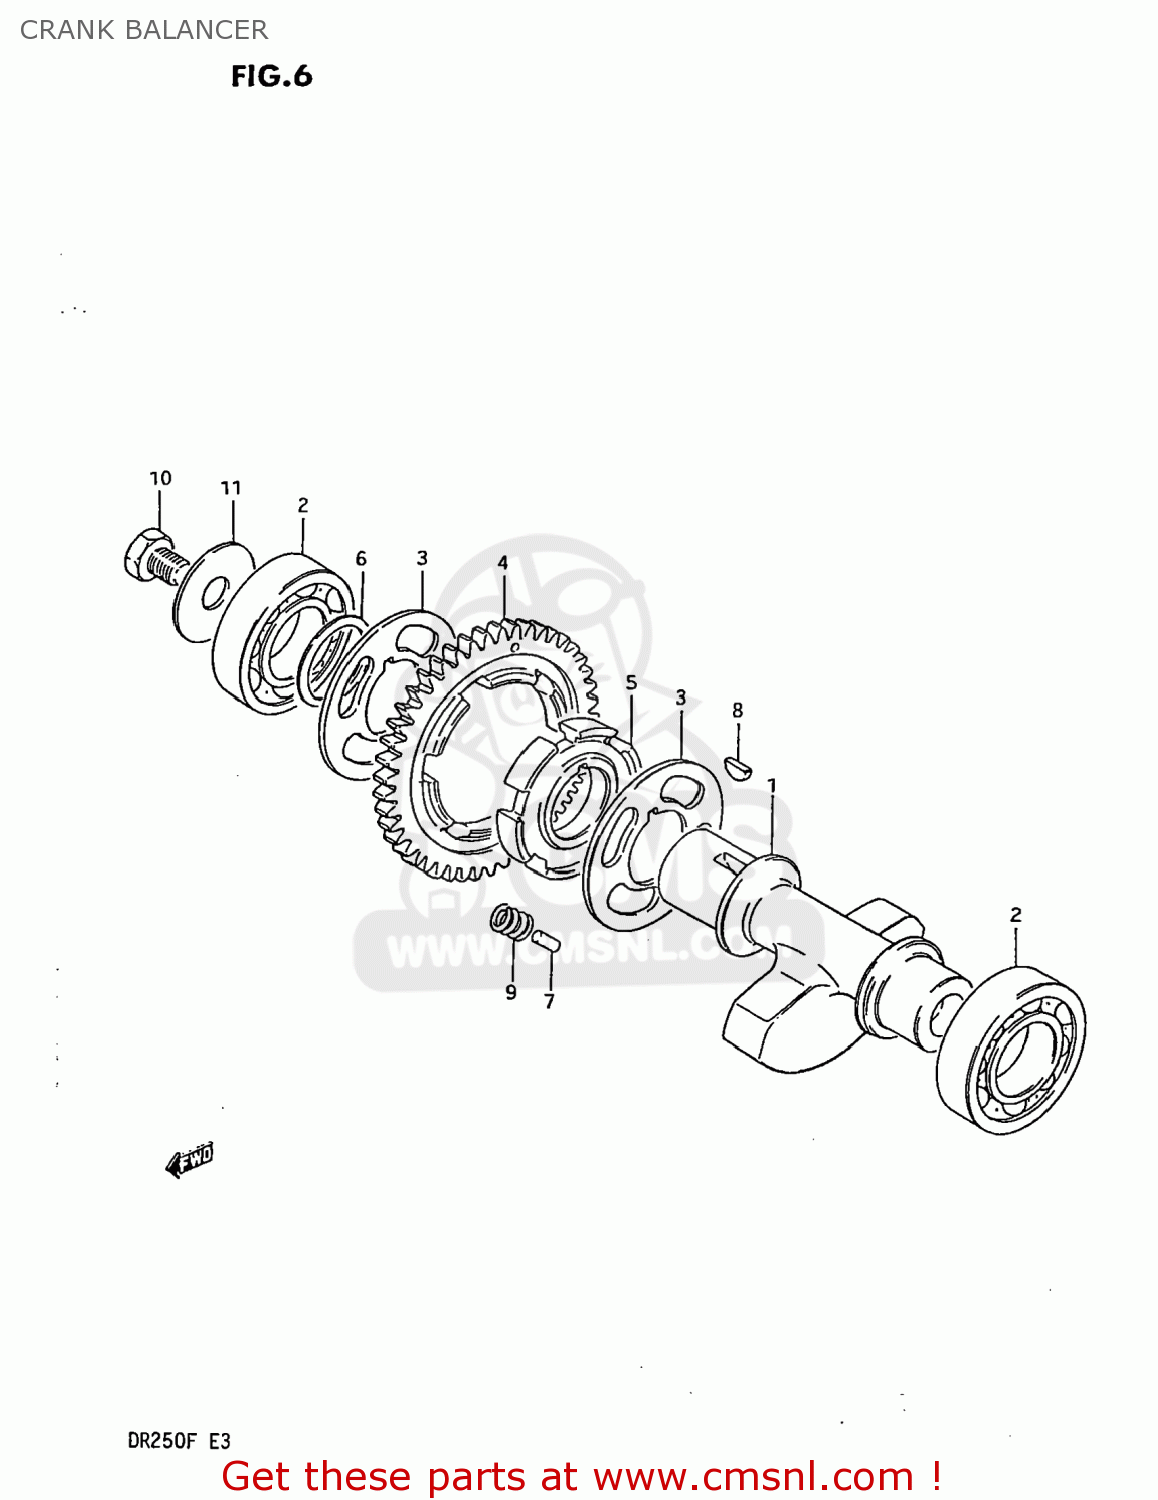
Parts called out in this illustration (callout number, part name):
1	BALANCER,CRANKSHAFT
2	BEARING
3	WASHER
4	GEAR,CRANK BAL DRIVEN(NT:46)
5	RACE,CRK BAL DRIVEN GR INNER
6	SHIM
7	PIN
8	KEY 4MM
9	SPRING
10	BOLT ,12X16
11	WASHER
